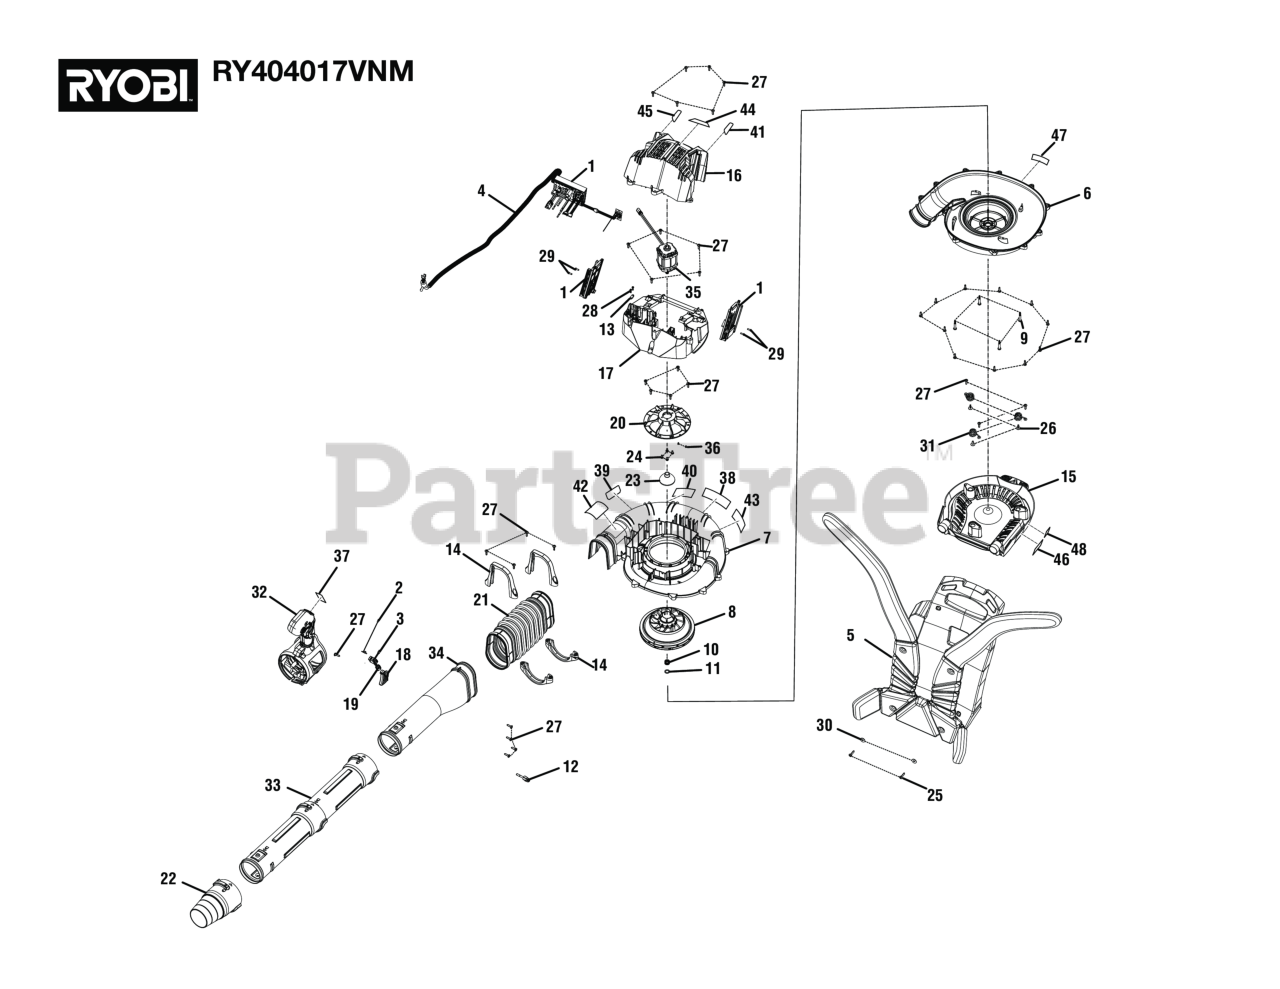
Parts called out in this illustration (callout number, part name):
1	Motor Controller and Battery Holder Assembly
2	Turbo Switch
4	Wire Assembly
5	Upper Frame and Strap Assembly
6	Outer Volute Assembly
7	Inner Volute Assembly
8	Fan Assembly
9	Shoulder Screw (M5 x 40 mm, T25 Torx Truss Hd. T.F.)
10	Wavy Spring (ID6.51 x HGT9.52)
11	Washer (OD18 x ID12.15 x 1.5t)
12	Blower Knob (1.35 in [34.3 mm])
13	Cord Clamp
14	Clamp Assembly
15	Lower Frame Assembly
16	Housing Cover Assembly
17	Bottom Housing Cover
19	Switch Cap
20	Motor Mount
21	Bellows Tube
22	Speed Nozzle Assembly
23	Drive Coupler
24	Screw w/Lock Washer (M5 x 8 mm, Pan Hd.)
25	SCREW (10-14 X 1 in.)
26	Screw (10-14 x 16 mm)
27	Screw (10-14 x 19 mm, T25 Torx Truss Pan Hd. T.F.)
28	Screw (M4 x 14 mm, T15 Torx Pan Hd.))
29	Screw, M4-18 x 12mm, T20 Torx Pan Head
30	Washer (OD16 x ID6.8 x 1.5t)
32	Throttle Handle and Cruise Control Assembly
33	Upper Blower Tube
34	Handle Tube
36	SCREW, CH M3 PH B\L=6MM
37	Turbo Label
38	RYOBI 40V HP Logo Label
39	Battery Warning Label
40	CFM MPH Label
41	Warning Label (French)
42	Warning Icon Label
43	Whisper Logo Label
44	40V HP Brushless Label
45	Warning Label (Spanish)
46	Data Label
47	Hair Ingestion Warning Label
